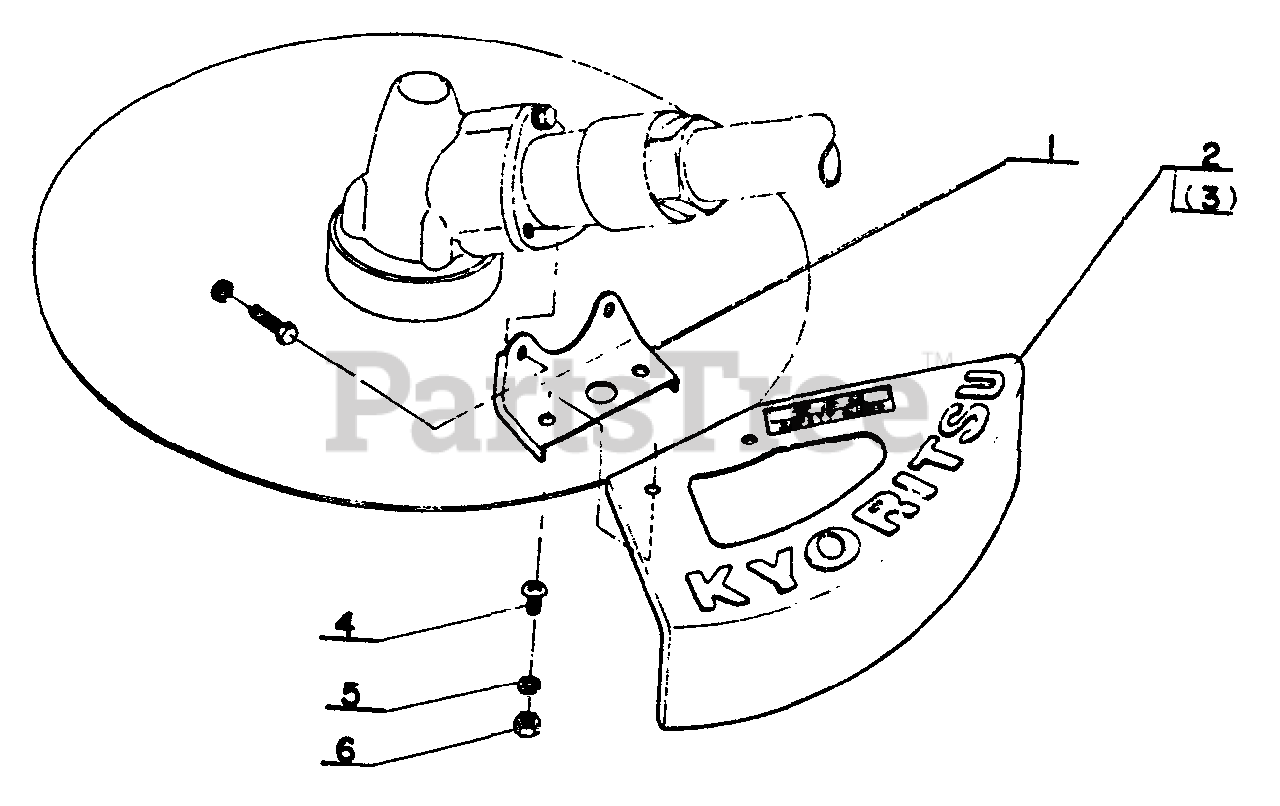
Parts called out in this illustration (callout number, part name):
1	Set plate, safety guard
4	SCREW - 5X8
5	LOCKWASHER - 5
